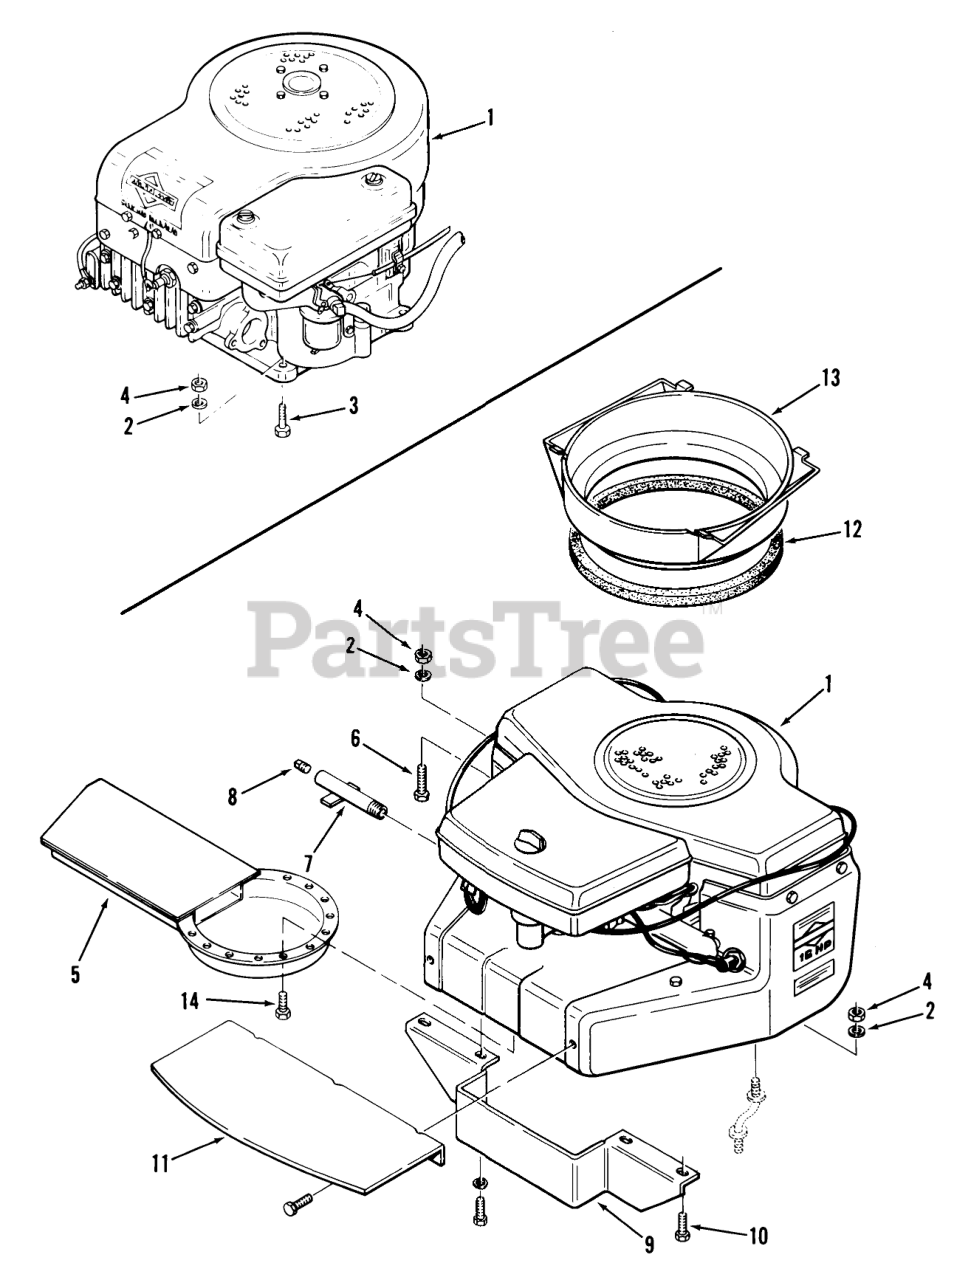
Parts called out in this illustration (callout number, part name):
1	Engine-8HP-B&S Model 191707, Type 1136-01
1	Engine-8HP-B&S Model 191707, Type 1160-01 02-08BP03 Only.
1	Engine-11HP-B&S Model 252707, Type 0206-01
1	Engine-11HP-B&S Model 252707, Type 0222-01 02-11BX03 Only
1	Engine-11HP-B&S Model 252707, Type 0209-01
1	Engine-16HP-B&S Model 401707, Type 0111-04
1	Engine-16HP-B&S Model 401707, Type 0632-01 Later Production
2	WASHER 5/16 SAE
3	Bolt
4	Nut
5	Exhaust Deflector B-165 Only
6	Bolt
7	Drain Pipe B-165 Only
8	Plug-Pipe 1/4-18
9	Duct-Rear 216-5 Only
10	Bolt
11	Duct-Front B-165 Only
12	Insulation-Hood B-165 Only
13	DUCT-AIR INTAKE
14	SCREW 8-32X3/8
